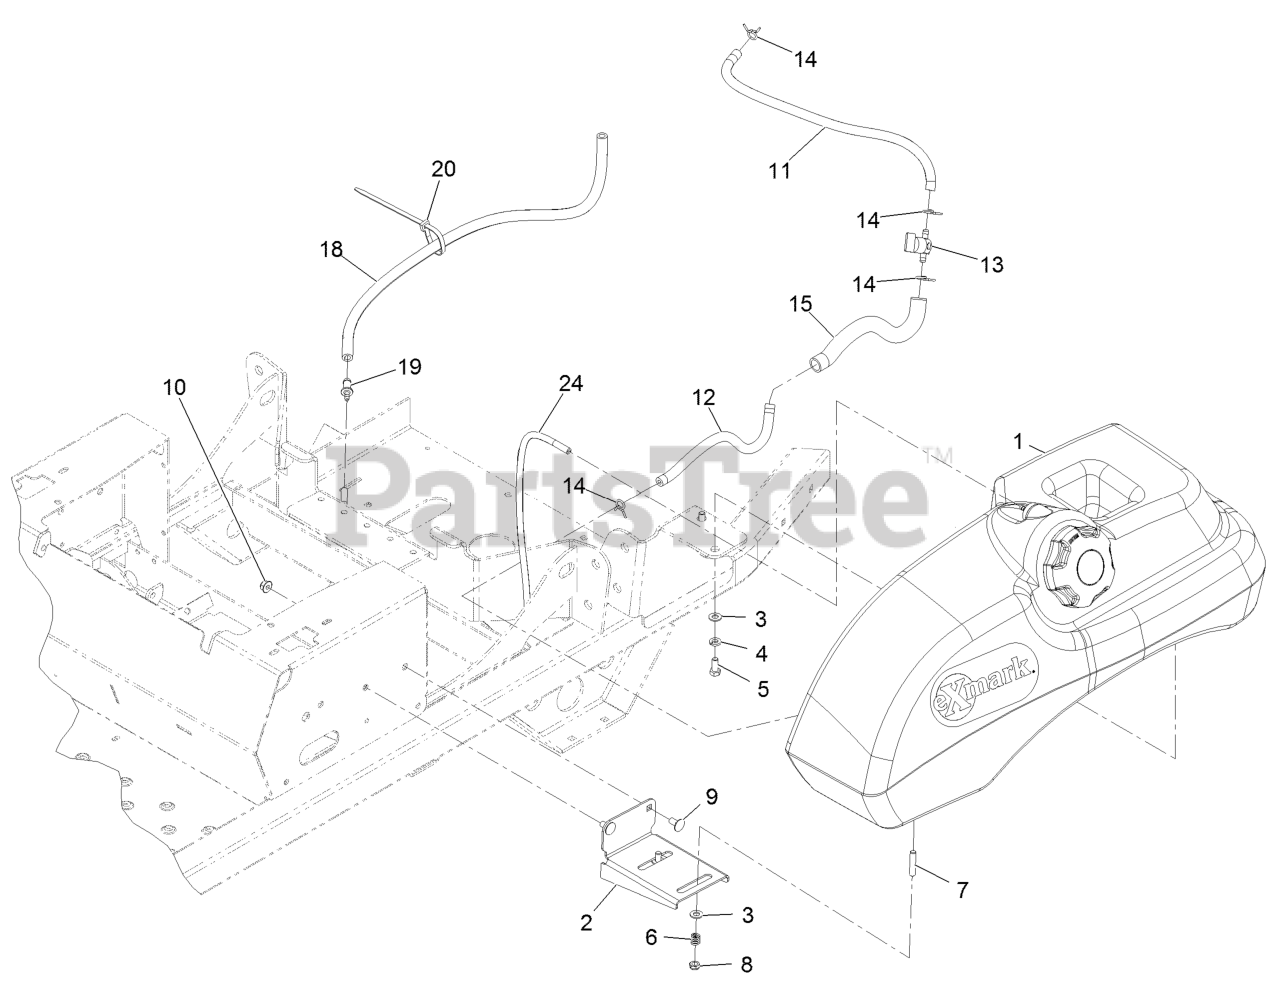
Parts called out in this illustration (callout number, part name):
1	ASM-FUEL TANK
2	BRACKET-TANK AND FENDER
3	WASHER-PLAIN
4	WASHER-LOCK
5	SCREW-HH
6	SPRING-TANK, FUEL
7	STUD
8	NUT-LOCK, NI
9	SCREW-CARR
10	NUT-HF, NI
11	HOSE-FUEL
12	HOSE-FUEL
13	VALVE-FUEL
15	CONDUIT-FUEL LINE
18	HOSE-FUEL
19	FITTING-ORIFICE, STRAIGHT
20	TIE-PLASTIC
24	HOSE,EMISSIONS
